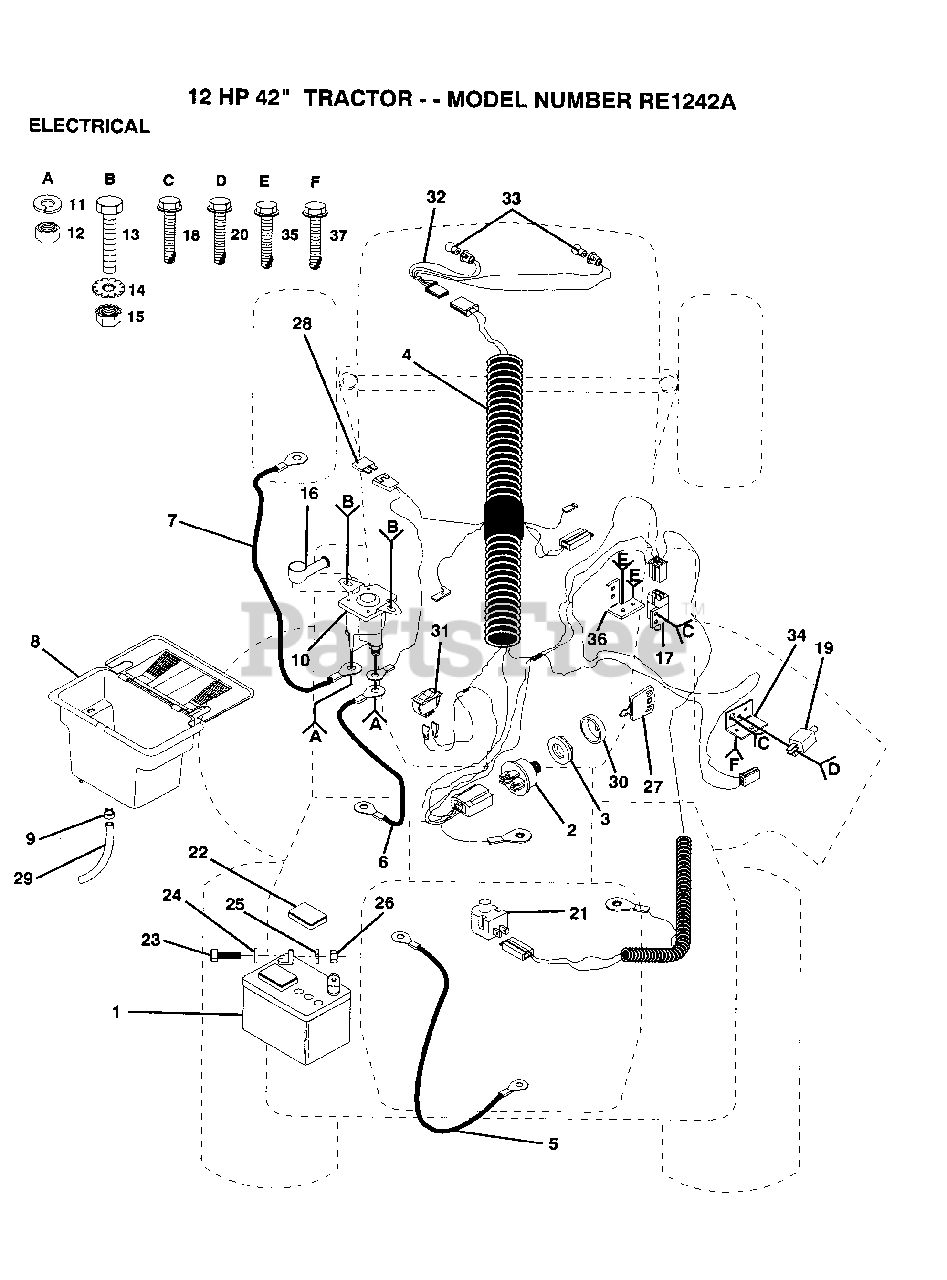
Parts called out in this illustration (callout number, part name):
3	NUT IGNITION
4	IGN HARNESS
5	CABLE T
7	"CABLE T, BATTERY"
9	HOSE CLAMP T
12	NUT
13	BOLT
15	NUT
17	SWITCH INTERLOCKT
18	SCREW
19	SWITCH-INTER. GT
20	SCREW
21	SWITCH SEAT
22	"CAP,BATTERY "
23	BOLT LT
24	WASHER
25	LOCKWASHER
27	KEY
28	FUSE HYT
31	SWITCH LT
34	BRACKET LT
35	SCREW
36	SWITCH BRACKET
37	SCREW
